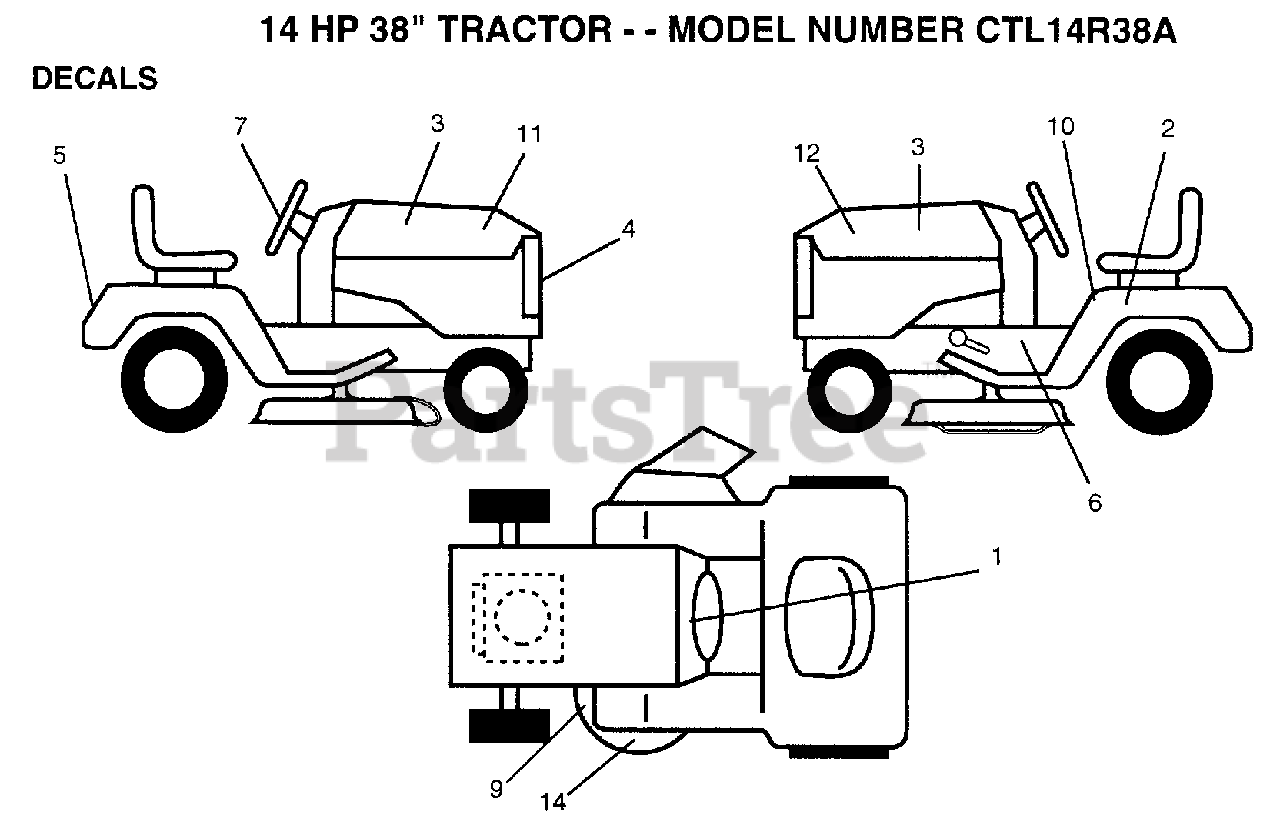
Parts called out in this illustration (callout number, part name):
1	DECAL.INST.OPER
1	VALVE CAP
2	DECAL.FEND.QUICKS
2	VALVE STEM LT
3	DECAL.INS.HOOD
3	FITTING LT
4	GRILL DECAL
5	FENDER DECAL
5	TUBE.5.3/4.5/6
6	IND HGT DECK DECA
6A	"RIM ASM REAR 8"""
7	"DECAL,STR WHL"
7	HUB CAP
8	"FLANGE, BEARING"
9	DECAL
9	WASHER
10	DECAL
11	DECAL HD RLY RH
12	DECAL HD RLY LH
